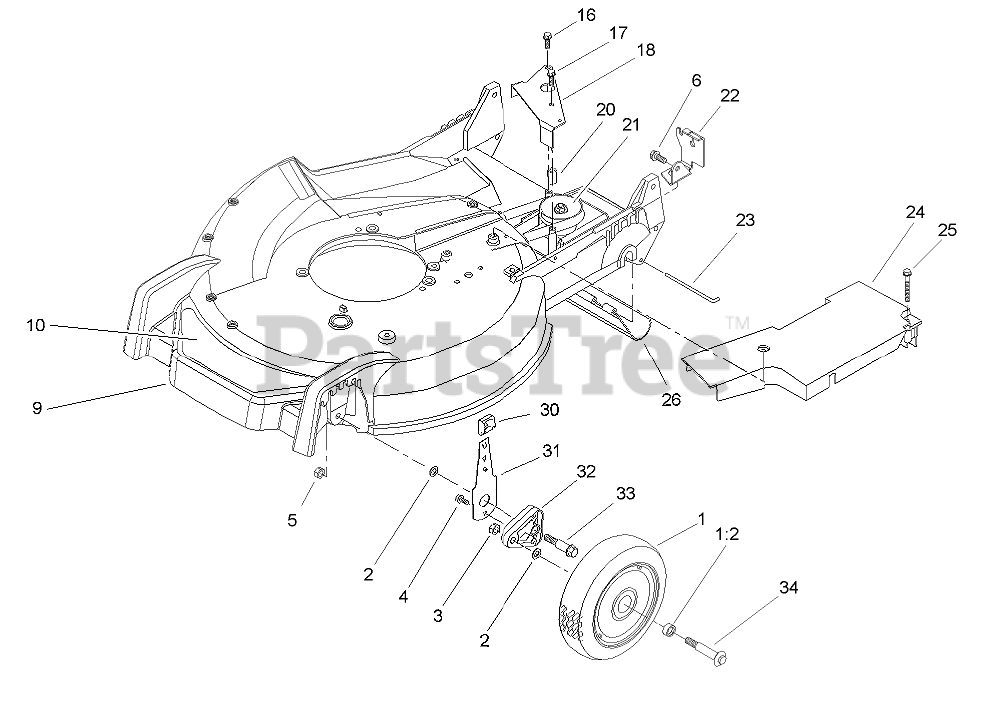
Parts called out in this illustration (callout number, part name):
1	WHEEL ASM
1:2	BUSHING
2	WASHER
4	SCREW-HWH
5	NUT-LOCK
6	SCREW-HWHTF
9	HOUSING ASM
10	DECAL-HOUSING
16	SCREW-HWHTF
17	SCREW-HWHTF
18	BRACKET-TRANSMISSION ACTUATOR
20	BUSHING-PLATE, ACTUATOR
21	GEAR CASE ASM
22	BRACKET-CABLE, TRACTION
23	ROD-SHIELD
24	COVER-BELT
25	SCREW-HHFTF
26	SHIELD-TRAILING
30	KNOB-ARM
31	FRONT SPRING ARM ASM
32	ARM-PIVOT, FRONT
33	BOLT-SHOULDER
34	BOLT-SHOULDER
